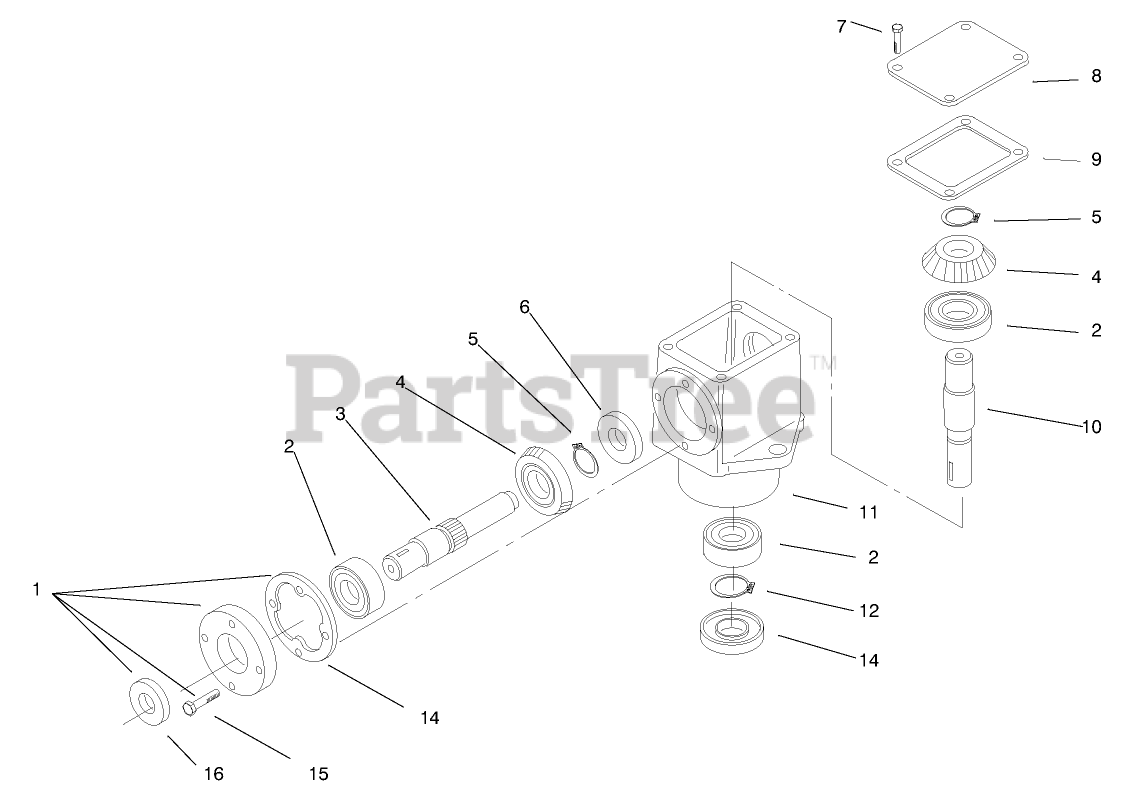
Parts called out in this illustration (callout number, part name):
1	Retainer Asm
2	Bearing
3	Shaft-Input
4	Gear-Miter
5	Ring-Snap
6	Bearing
7	Screw
8	Cover
9	Gasket
10	Shaft-Output
11	Housing
12	Ring-Snap
14	Gasket
15	Ring Set (STD)
16	Oil Seal
